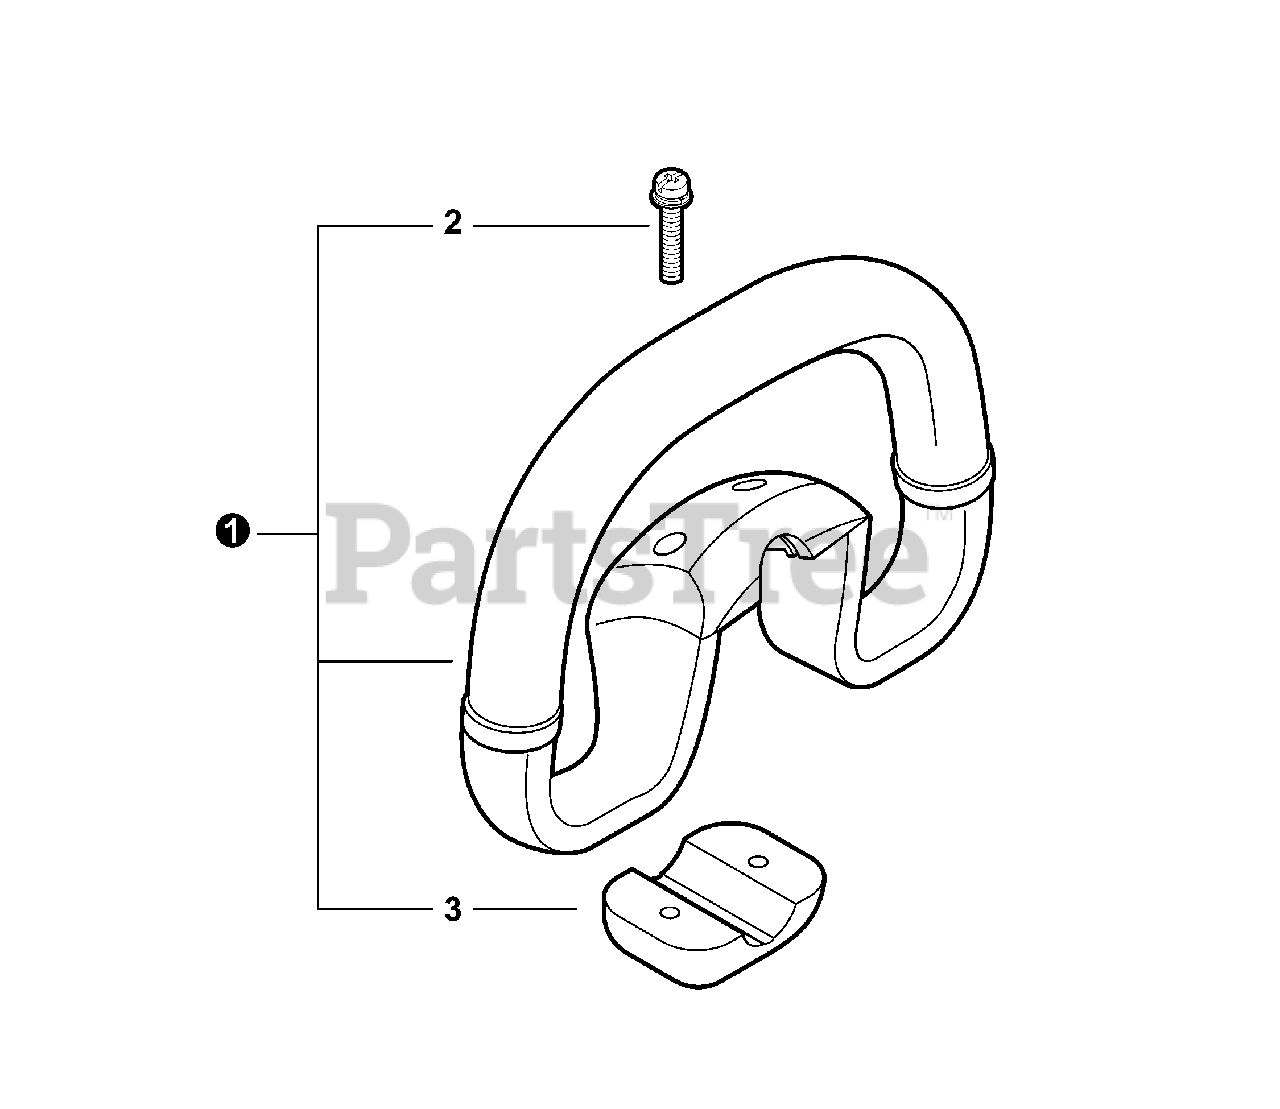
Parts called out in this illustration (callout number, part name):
1	HANDLE ASSY - SUPPORT
2	SCREW 5×40
3	BRACKET, HANDLE
